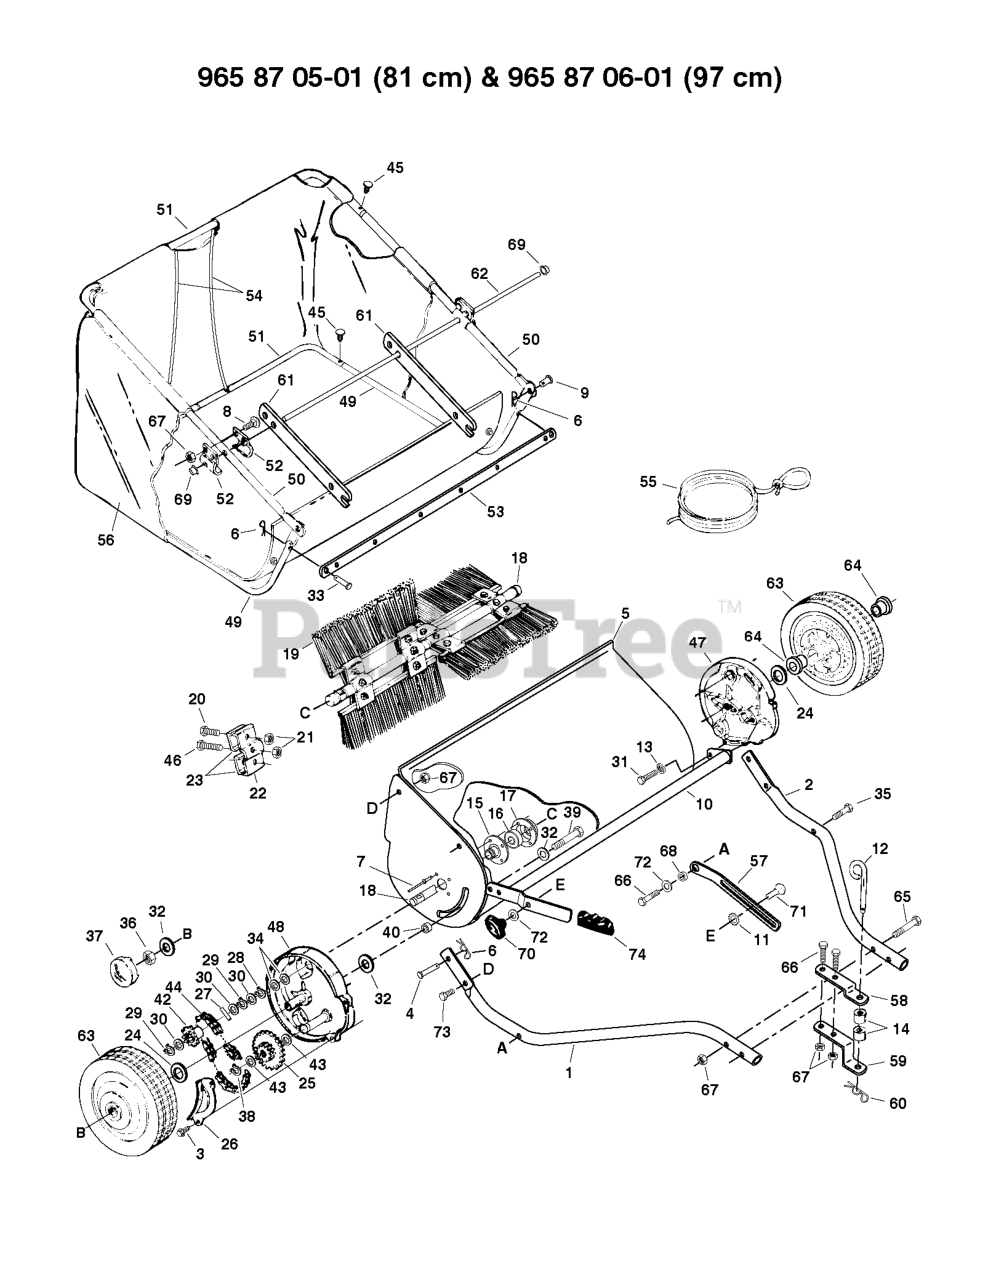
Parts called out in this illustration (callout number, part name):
1	DECAL
2	DECAL BTRY SYMBOLS
3	DECAL.HOOD.HUSQVARNA.INTERNATI
4	DECAL
6	DECAL PARK BRAKE
7	DECAL.STEERING.HUSQ.BLUE
10	DECAL READ OWNER'S MAN SYMS
13	DECAL.INTERNATIONL.CUTFINGER
14	DECAL V BELT SCHEMATIC
15	DECAL DECK "B" 42"
16	DECAL
